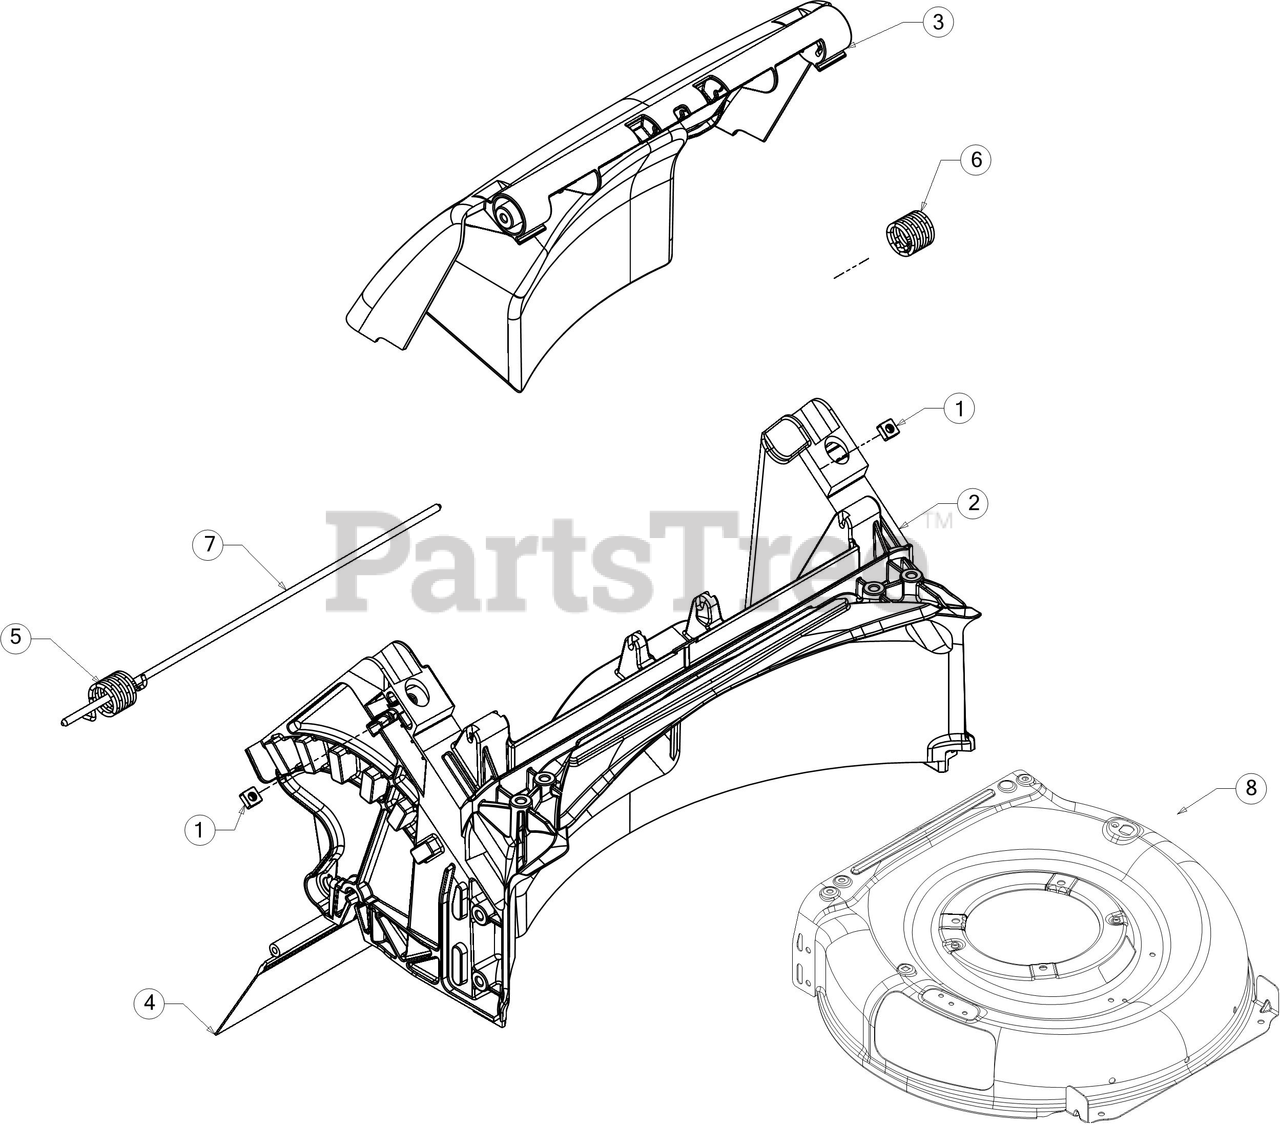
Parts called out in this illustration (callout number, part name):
1	SQUARE NUT 1/4-20
2	DOOR ASSEMBLY
4	TRAILSHIELD
5	TORSION SPRING (RH)
6	TORSION SPRING (LH)
7	REAR DOOR PIVOT ROD
8	21" DECK (3N1)
